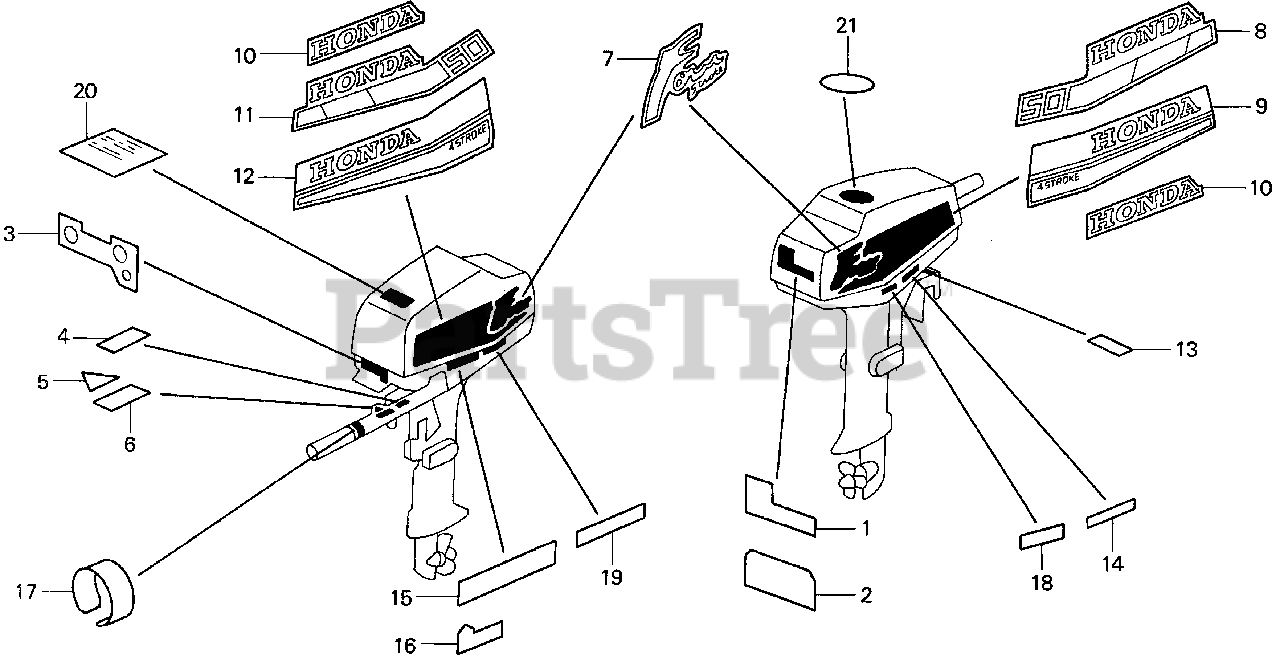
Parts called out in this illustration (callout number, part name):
2	EMBLEM, RR.
3	LABEL, INDICATION
4	MARK, STOP SWITCH
8	STRIPE, R. SIDE COVER (NOT AVAILABLE)
11	STRIPE, L. SIDE COVER
14	MARK, CHANGE
16	MARK, OIL CAUTION
17	MARK, THROTTLE
18	CAUTION, STORING
20	MARK, OPERATOR CAUTION
